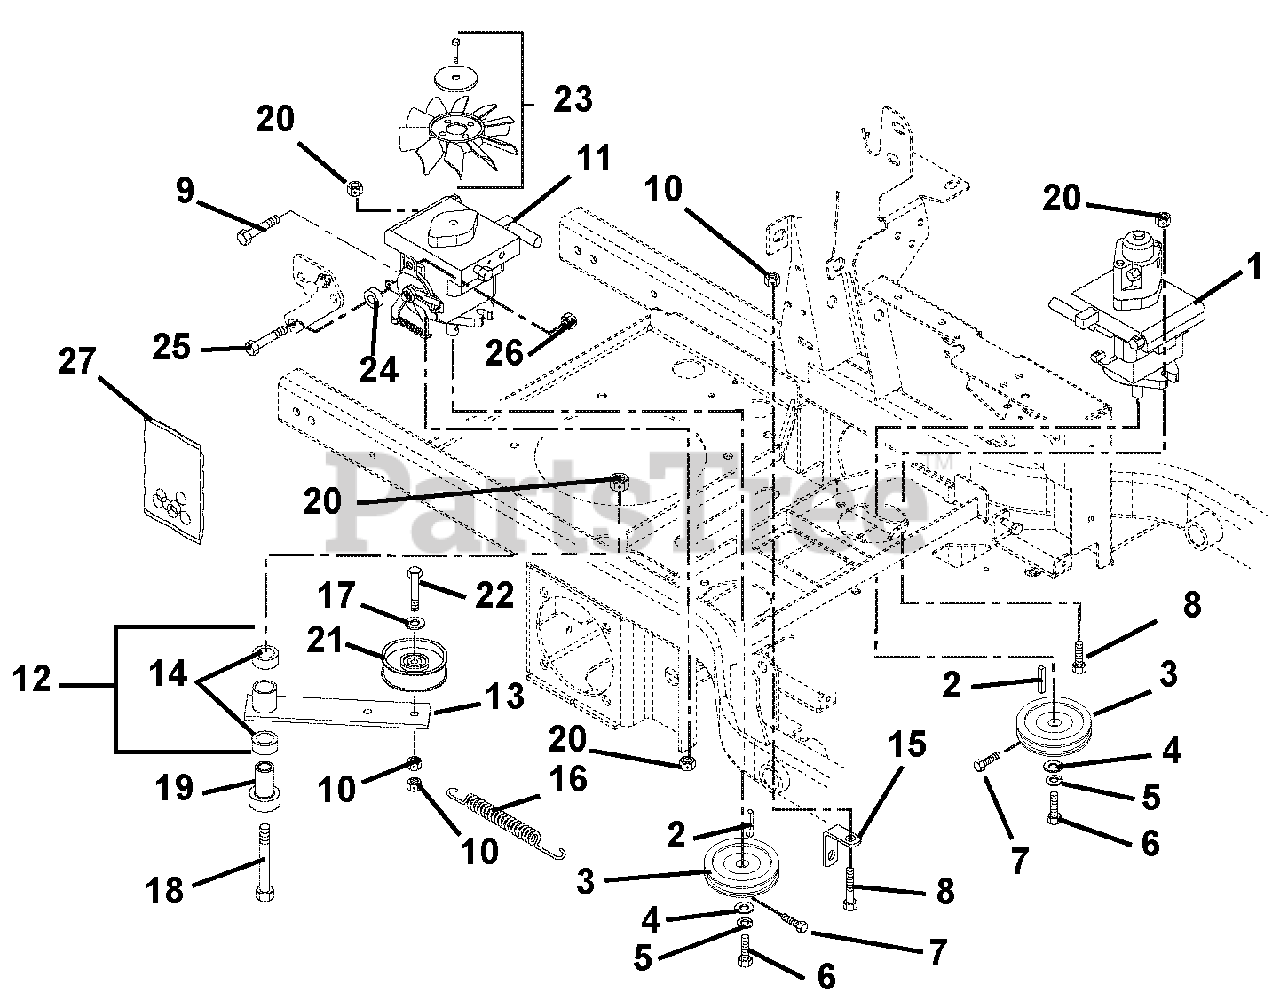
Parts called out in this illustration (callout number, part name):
1	Pump, Hydraulic BDP-21 with Auxiliary
2	Key, Square 5 x 5 x 30mm Plain
3	Sheave, Poly V .671 x 4.125
4	Washer, Flat Steel .281 x 1.00 x .063
5	Washer, Locking .25 x .062
6	Bolt, Hex M6 x 1.0 x 12
7	Screw, Socket Head .25-20 x .50
8	Bolt, Hex .50-13 x 1.50 Grade 5
9	Bolt, Hex .31-18 x .75 Grade 5
10	Nut-Locking-Top-Flange .38-16
11	Pump, Hydraulic BDP-21 with Thru Fan
12	Assembly, Idler Arm Guard Drive (Includes 13 & 14)
13	Weldment, Idler Arm Ground Drive
14	Bearing, 1.00 x 1.12 x .75
15	Anchor, Spring Idler
16	Spring, Tension .120 x .845 x 6.500
17	Washer, Flat Steel .39 x .75 x.125
18	Bolt, Hex .50-13 x 3.50 Grade 5
19	Bearing, Pedestal Powdered Metal
20	Nut, Locking Top Flange .50-13
21	Idler, Flat 4.00 x 1.06
22	Bolt, Hex .38-16 x 2.25 Grade 5
23	Fan, Hydro Pump Cooling
24	Spacer .318 x .43 x .375
25	Bolt, Hex .31-18 x 1.25 Grade 5
26	Nut, Locking Top Flange .31-18
27	Kit, Pump Seal (BDP-21L)(One kit required for each pump)
